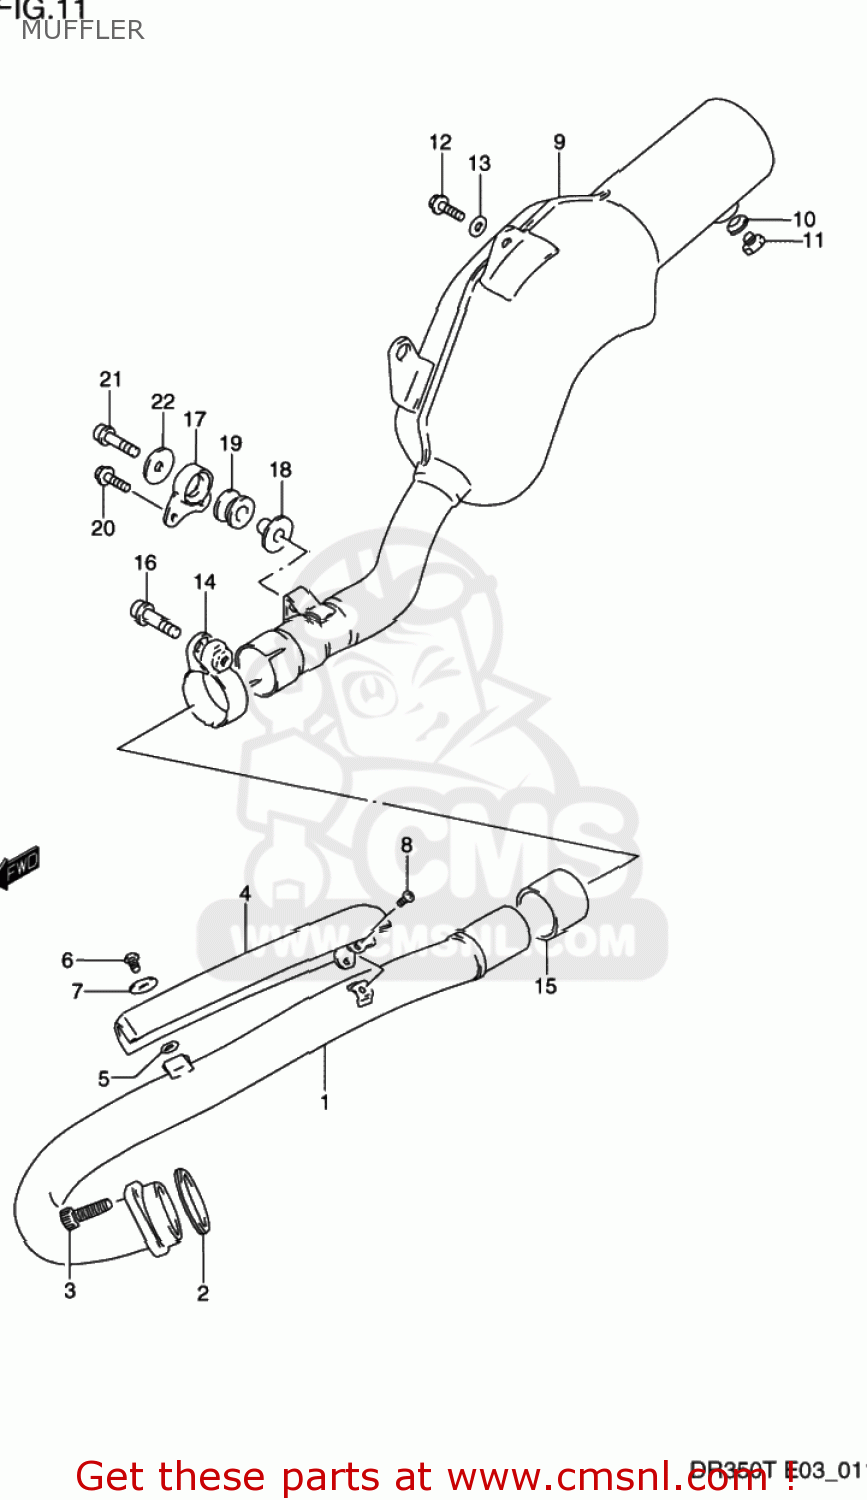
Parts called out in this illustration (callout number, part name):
1	PIPE,EXHAUST
2	GASKET,EXHAUST (NAS)
3	BOLT
4	COVER,EXHAUST PIPE
5	GASKET(5.8X13X1.4) (NAS)
6	SCREW
7	WASHER(6.5X18X1)
8	SCREW
9	BODY,MUFFLER
10	GASKET(12.1X16.2X3.7) (NAS)
11	PLUG(12X9)
12	BOLT(8X20)
13	WASHER (8.5X19X2.3)
14	CLAMP,PREMUFFLER CONNECTOR,L
15	CONNECTOR,MUFFLER
16	BOLT
17	DAMPER,MUFFLER SUPPORT
18	SPACER(8.6X12X17.5)
19	CUSHION
20	BOLT 6X12
21	BOLT 8X35
22	WASHER (8.5X20X1.6)
